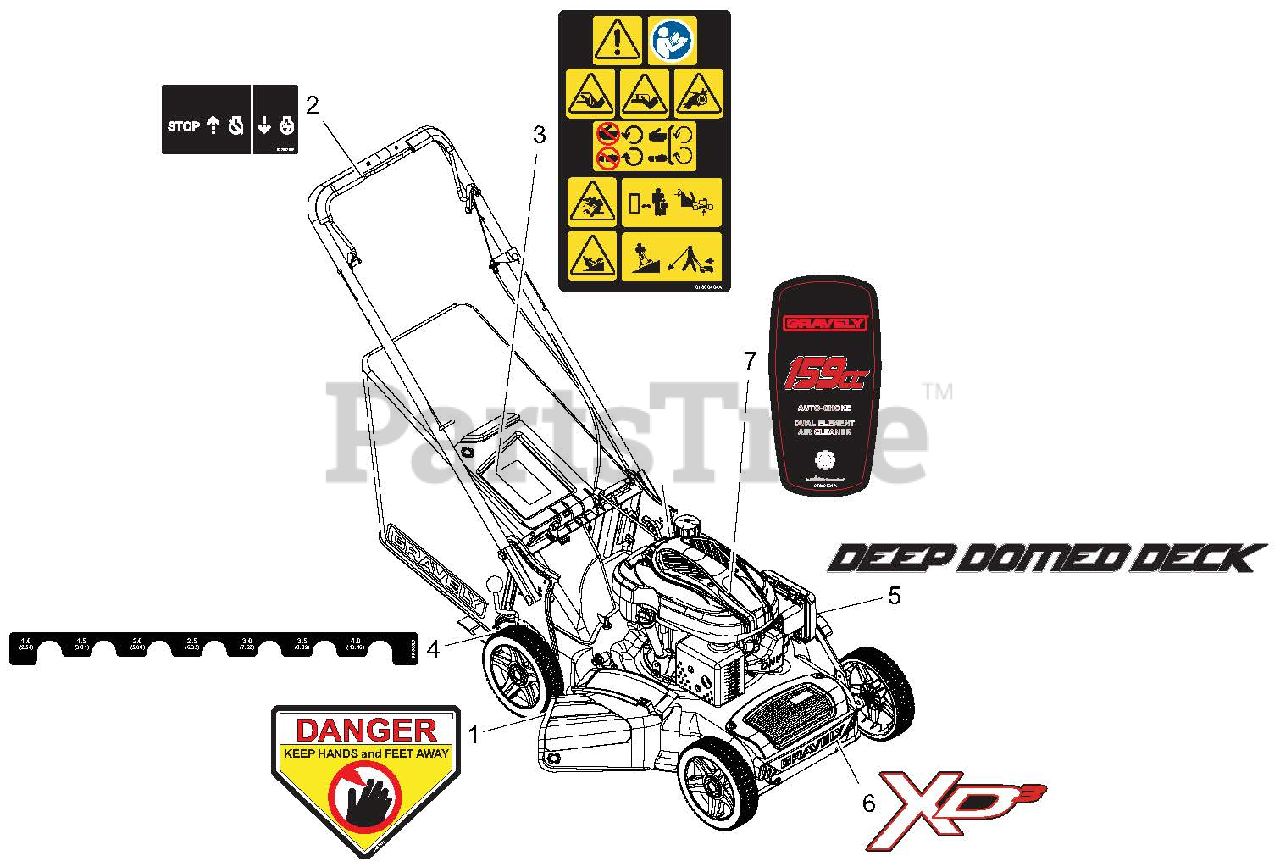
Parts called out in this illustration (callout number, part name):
1	DECAL, DANGER
2	DECAL, ENGINE CONTROL
3	DECAL, MAIN SAFETY WAW LM
4	DECAL, HOC
5	DECAL, DEEP DOME DECK
6	DECAL, GRAVELY XD3 STYLE
7	DECAL, ENGINE STYLE - GRAVELY
